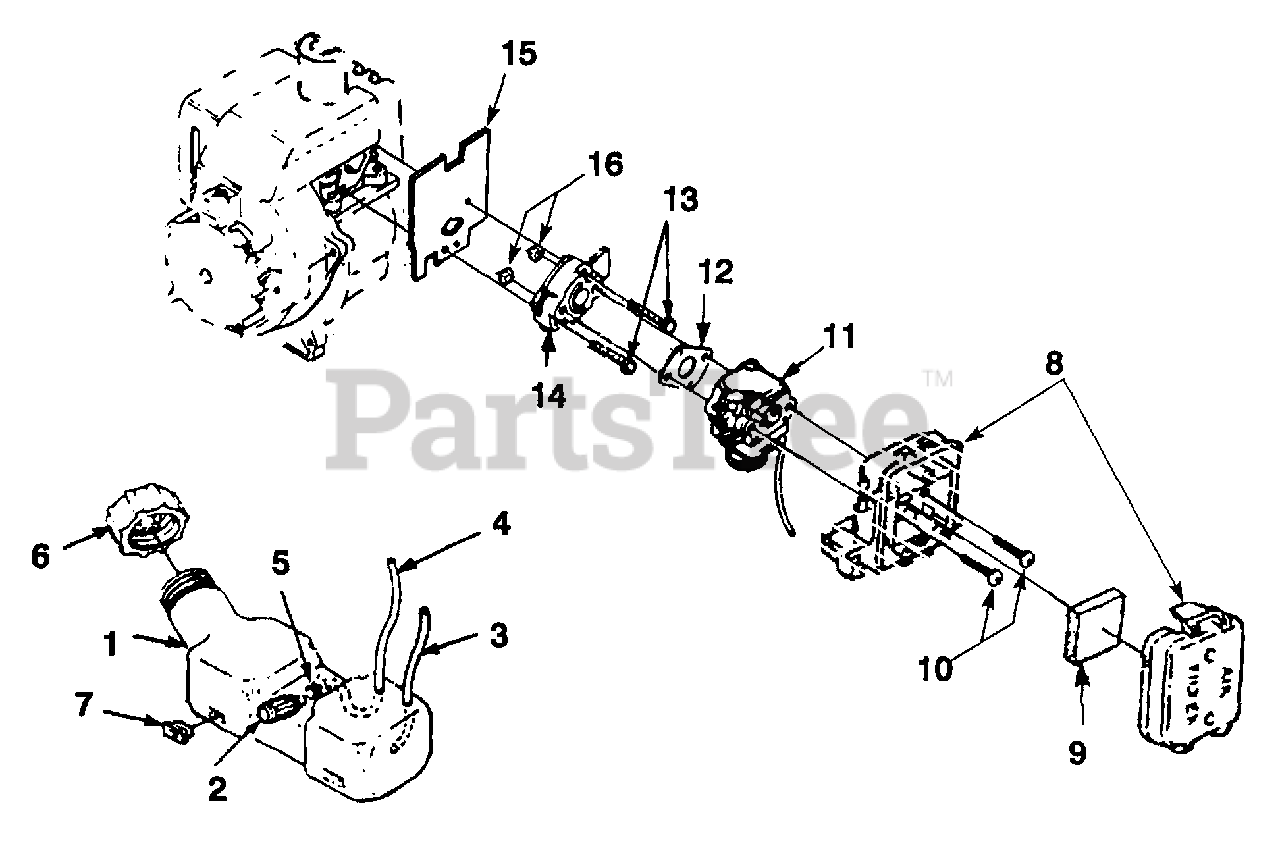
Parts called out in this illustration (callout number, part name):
1	Fuel Tank
2	Filter - Fuel
3	Tubing - Rubber (8")
4	Tubing - Rubber (8")
5	Clamp - Wire
6	Fuel Cap
7	Bumper - Rubber
8	Air Filter Kit
9	Air Filter
10	Screw - Sems Hex Hd (10-24 x 2 1/2")
11	Carburetor
12	Gasket, Carburetor
13	Screw, Sems (10-24 x 1")
14	Heat Dam
15	Heat Dam Gasket
16	Nut - Hex (10-24)
